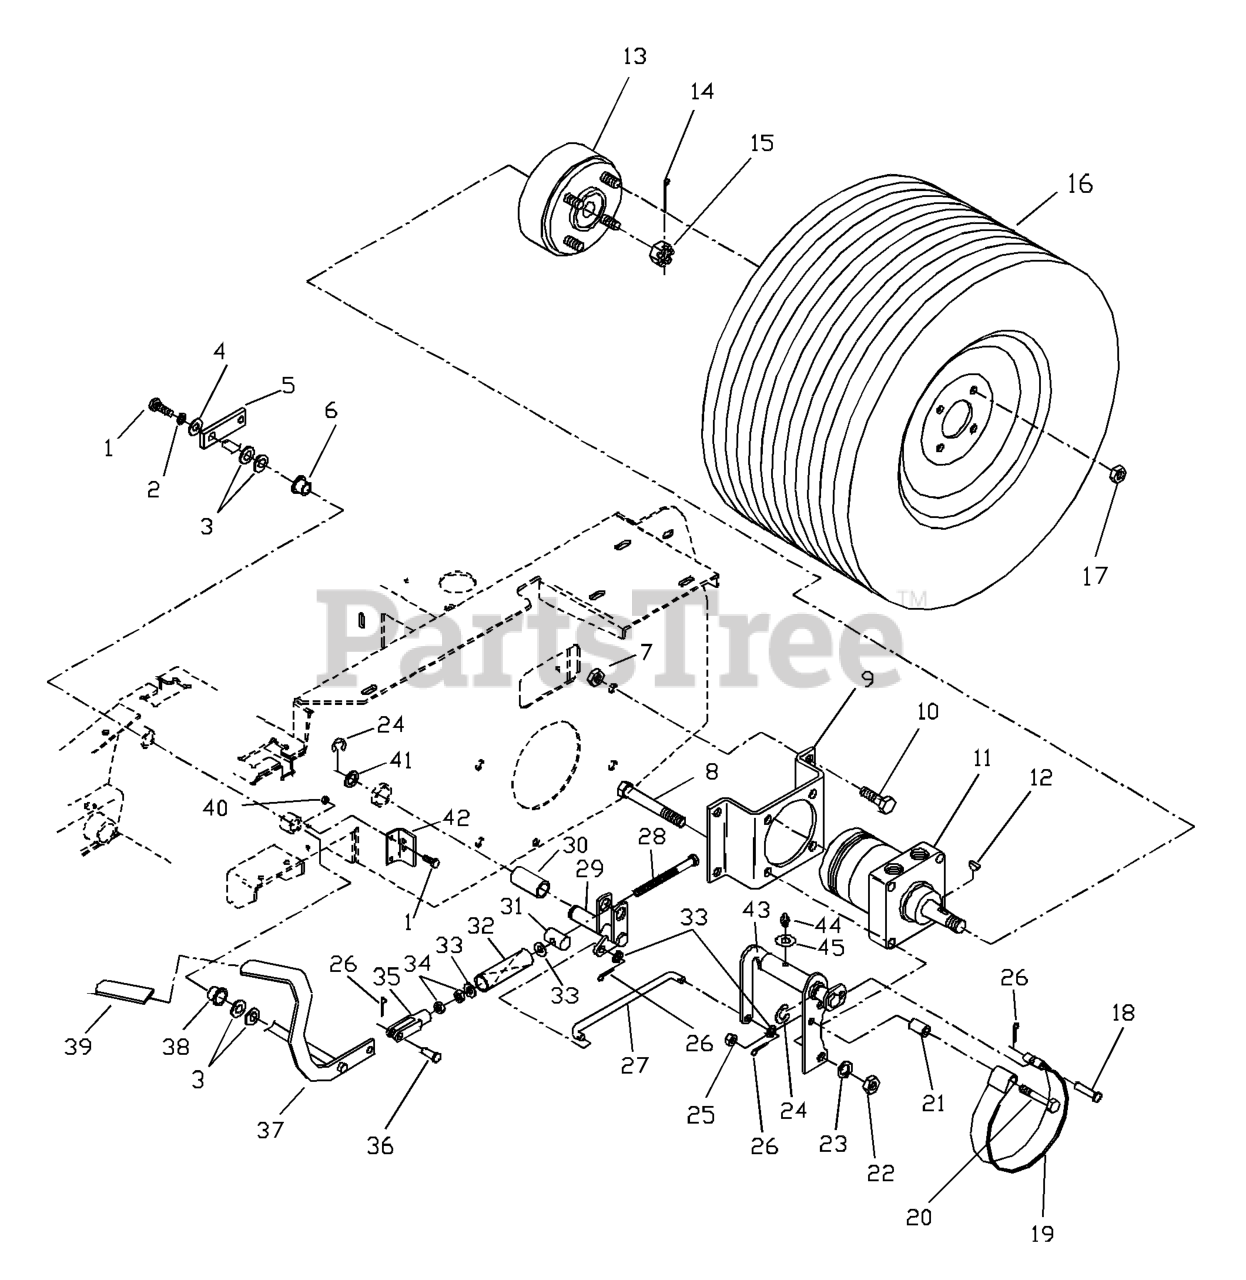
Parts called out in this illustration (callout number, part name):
1	HCS 1/4C X 3/4 HCS
2	LOCKWASHER 1/4"
3	WASHER, 7/16 DISC SPRING
4	WASHER 1/4 FLAT
5	ARM, PARK BRAKE
7	NUT 1/2-13 HEX NYLOC ZD
8	HCS 1/2C X 2 3/4
9	MOTOR STANDOFF - PAINTED
10	HCS 1/2C X 1 1/4 SERRATED HEAD
11	MB WHEEL MOTOR
12	WOODRUFF KEY
13	HUB W/BRAKE DRUM
14	COTTER PIN
15	CASTLE-NUT
16	TIRE.24X12-12.TURF.MASTER
16	RIM (REAR)
16	VALVE STEM TR-412
17	LUG NUT 1/2F
18	CLEVIS PIN, 3/8 X 1 1/2
19	BRAKE BAND
20	HCS 3/8 X 3 GD.8
22	NUT HEX 1/2
23	WASHER 1/2" SPLIT LOCK
24	E RING 3/4
25	NUT 3/8C CENTERBLOCK
26	RP_COTTER PIN 1/8 X 3/4
27	BRAKE LINKAGE, LT.
27	BRAKE LINKAGE, RT.
28	HCS 3/8F X SPECIAL
30	BRONZE BEARING
31	TRUNION PIN
33	WASHER 3/8 SAE FLAT
35	YOKE-3/8-24 PLTD
36	CLEVIS PIN 3/8 X 1 1/8
37	BRAKE LEVER WIDMT
39	GRIP, PARK BRAKE
40	NUT 1/4C CENTERLOCK
43	LT.BRAKE WLDMT
43	LOWER BELT SHIELD
44	ZERK
